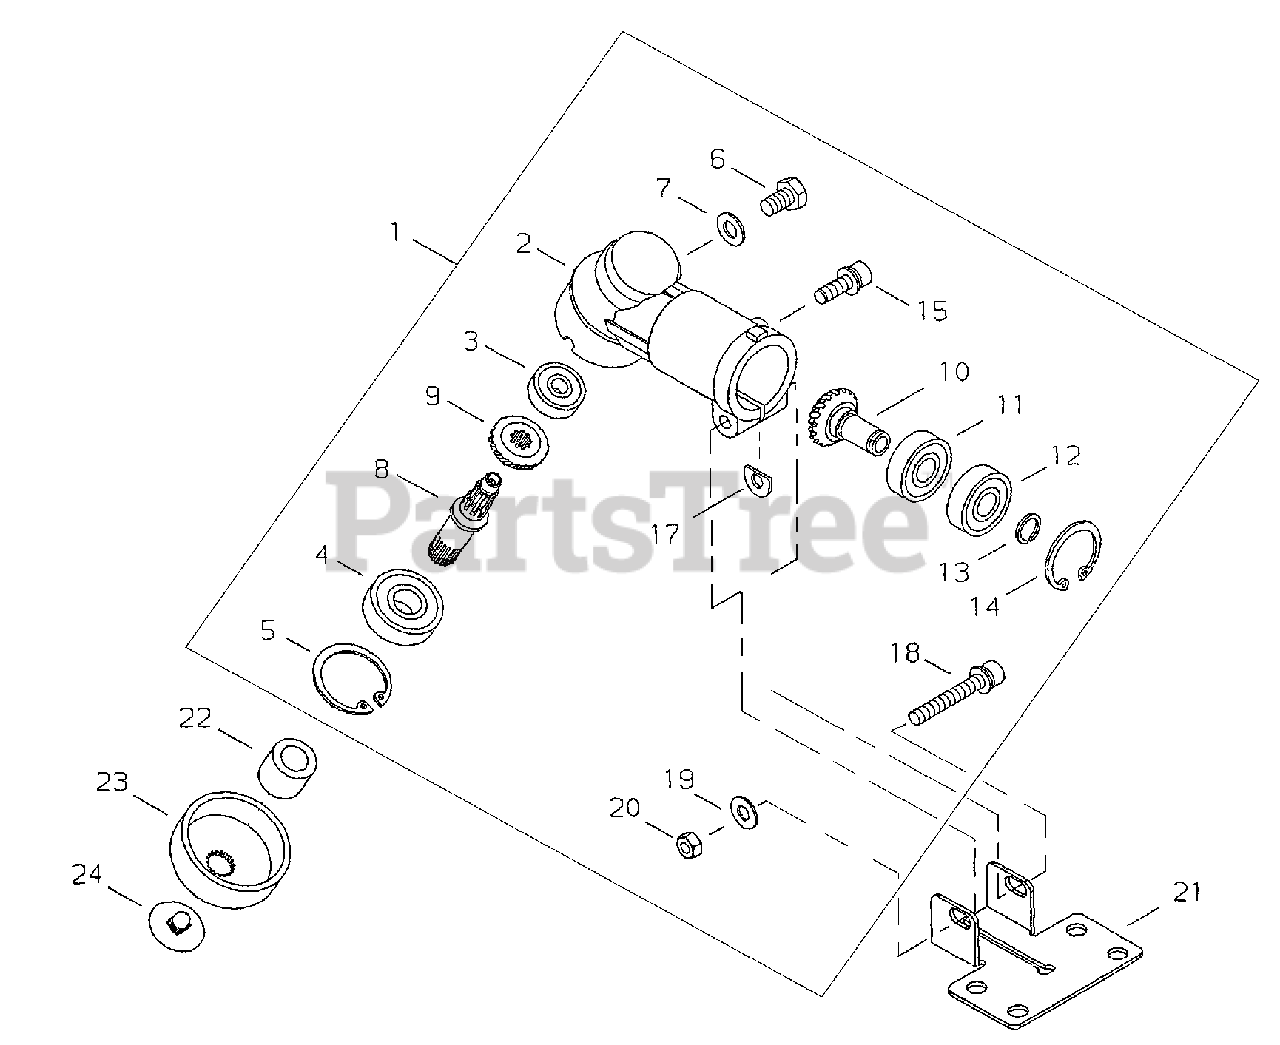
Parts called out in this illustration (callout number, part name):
2	GEARCASE
3	BEARING, BALL - 626
4	BEARING, BALL - 6000DDU
5	RING, RETAINING - 26
6	BOLT - 6X10
7	WASHER
8	GEAR - SHAFT
9	GEAR - BEVEL
10	GEAR - PINION
10-1	GEAR CASE ASSY
11	BEARING, BALL - 608
12	BEARING, BALL - 608ZZ
13	RING, RETAINING
14	RING, RETAINING - 22
15	SCREW - 5X16
17	SHIM
18	SCREW - 5X35
19	WASHER - 5
20	NUT - 5
21	CLAMP - LOWER
22	COLLAR
23	HOLDER
24	CLIP
